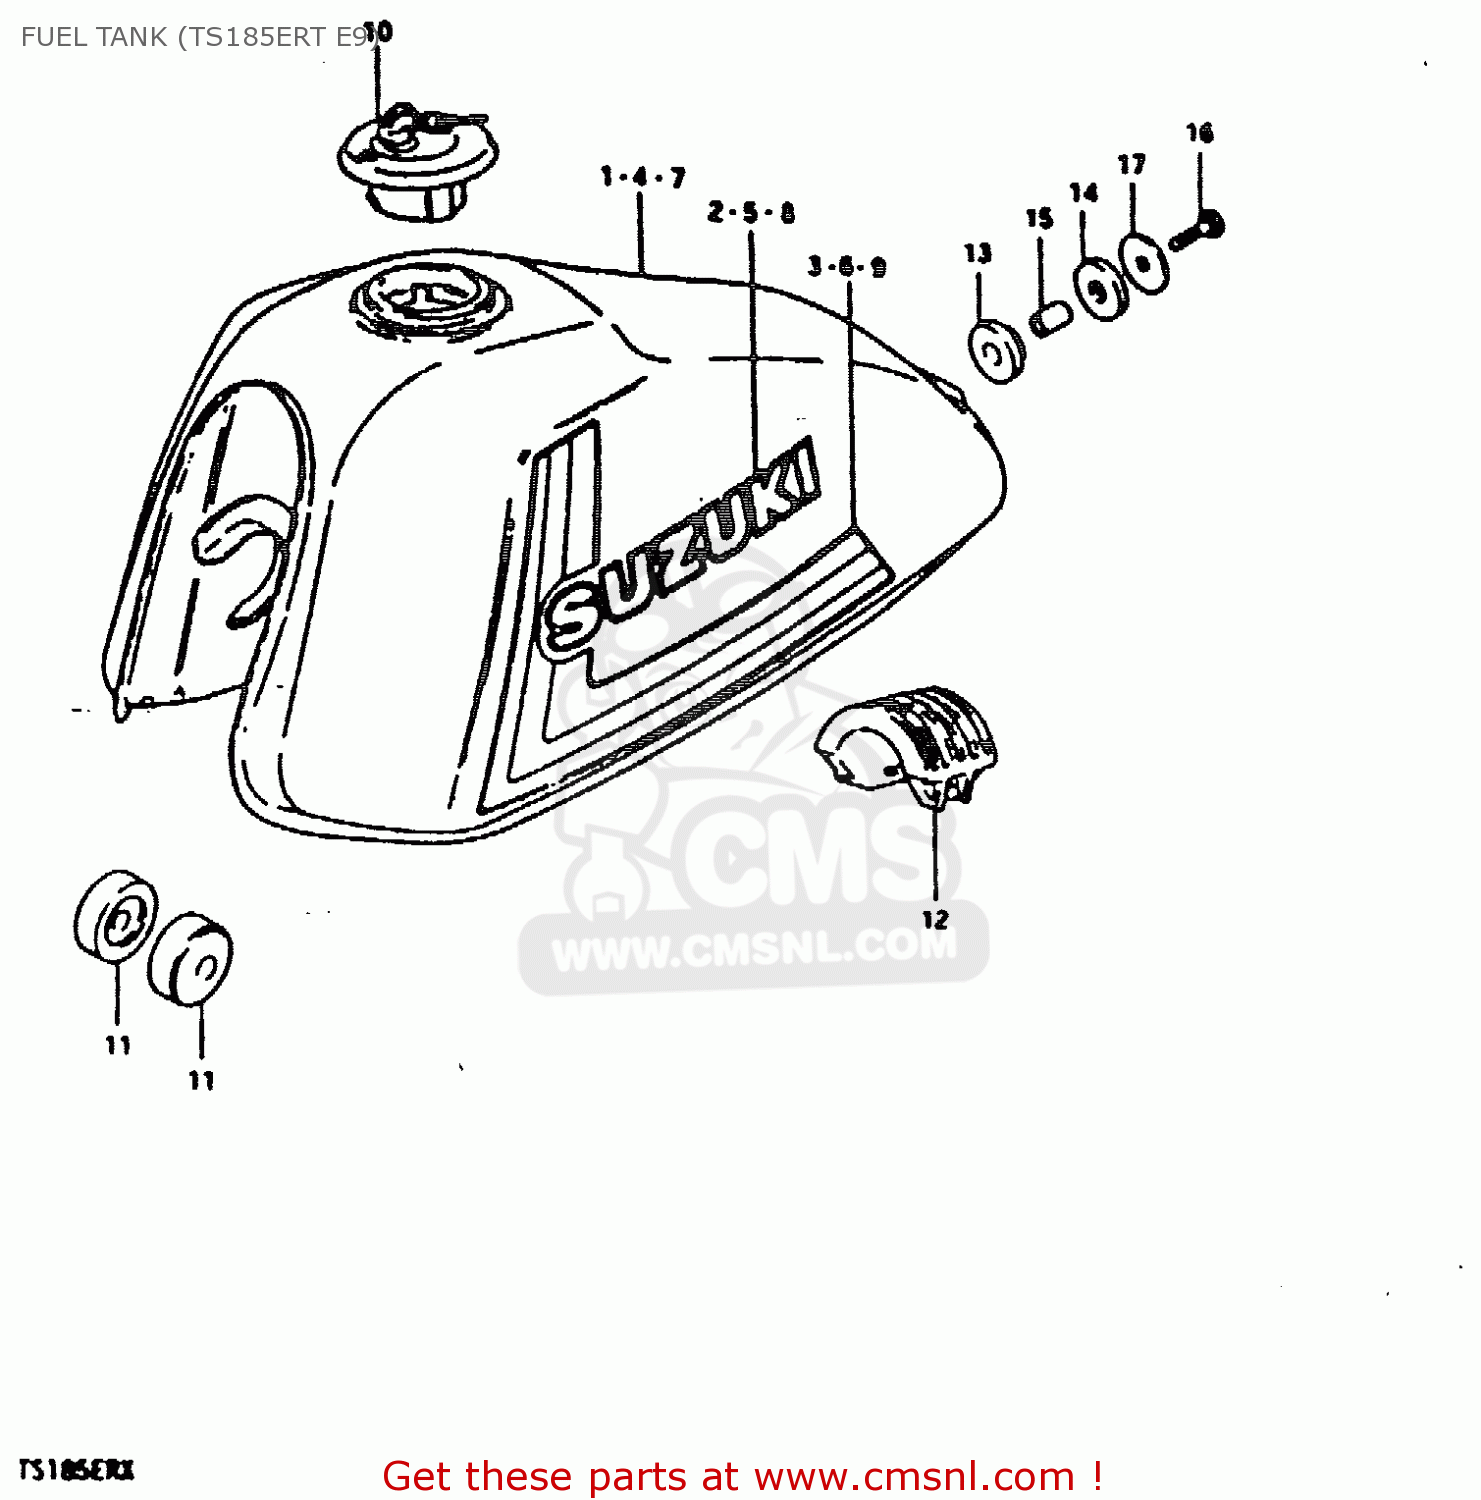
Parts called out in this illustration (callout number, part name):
1	TANK, FUEL (RED)
2	EMBLEM
3	TAPE SET
4	TANK, FUEL (BLUE)
5	EMBLEM
6	TAPE SET
7	TANK, FUEL
8	EMBLEM
9	TAPE SET
10	CAP SET,FUEL TANK
11	CUSHION
12	CUSHION,FUEL TANK
13	CUSHION
14	CUSHION
15	SPACER(8.5X12X19)
16	BOLT (8X30)
17	WASHER (8.5X29X1.6)
